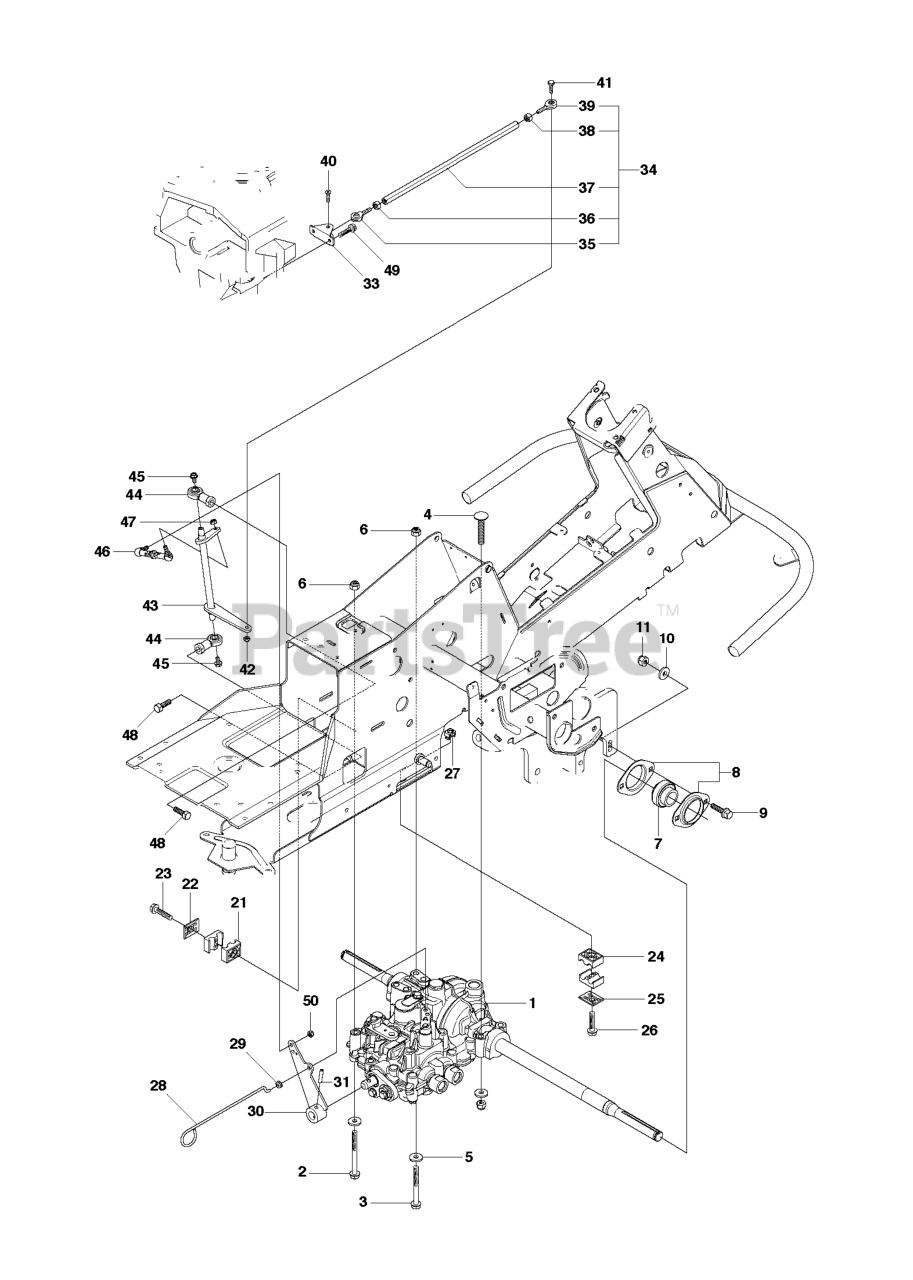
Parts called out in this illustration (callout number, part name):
1	TRANSMISSION SWE
5	WASHER BRB 8.4X17
6	LOCKNUT M8
8	BEARING HOUSING
9	BOLT
10	WASHER BRB 8.4X17
11	LOCKNUT M8
21	PIPE CLAMP
24	PIPE CLAMP
25	COVER PLATE
26	SCREW EHHFM
29	FUEL TANK BUSHING
34	ROD
42	NUT FLANGE - M6
45	SCREW EHHFM
46	ADJUSTING ROD
47	NUT FLANGE - M6
48	Screw M10x25
50	LOCKNUT M6
